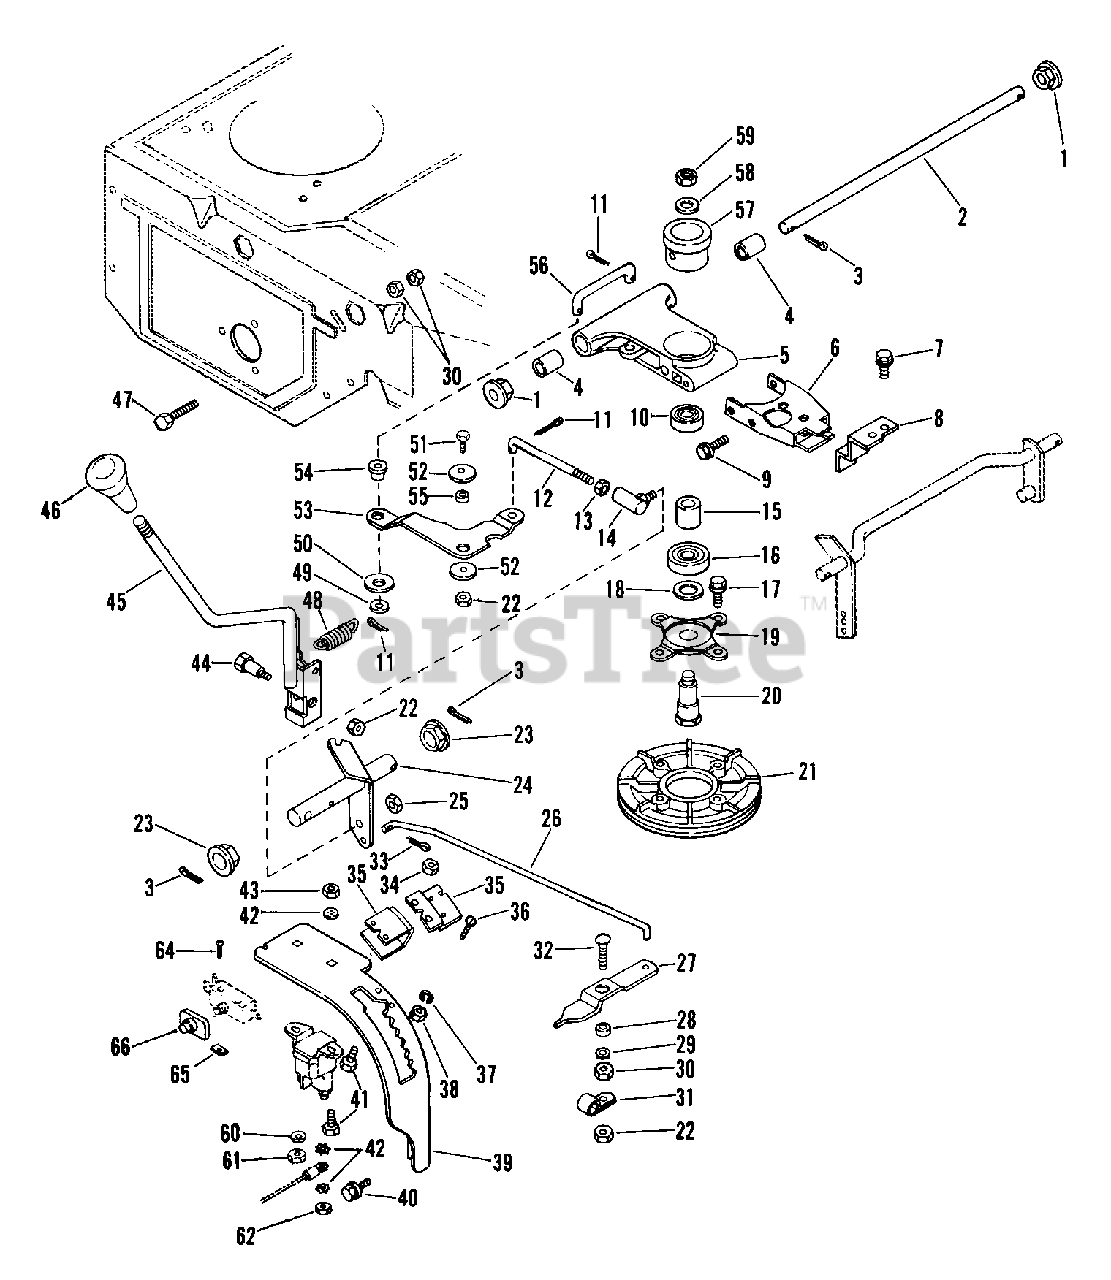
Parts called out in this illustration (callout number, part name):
1	FLANGE BUSHING
2	TRANSFER SHAFT
3	PIN-COTR .12X1.0 PL
4	BSHG-SLV .625X.750X.500 BR
5	CARRIER ASSEMBLY
6	CARRIER YOKE
7	SCR-TAP .312-18X.50 HWH PL TR
8	NEUTRAL STOP
9	SCR-TAP .312-18X.75 HWH PL TR
10	BRG-BALL .625X1.375X.44
11	PIN-COTR .09X.75 PL
12	SHIFT ROD
13	NUT-HEX .312-24 PL
14	SNAP IN BALL JOINT
15	BSHG-SLV .634X1.000X.465
16	BRG-BALL .750X1.781X.61
17	SCR-TAP.250-20X.62 HWH BLK ZC
18	WSHR-HDND-THRST .758X1.23X.031
19	DISC ADAPTER
20	SPINDLE BOLT
22	NUT-LK .312-18 GR A PL
23	FLANGE BUSHING
24	SHIFT ARM
25	NUT-LK-CTR .312-24 PL
26	INDICATOR ROD
27	INDICATOR
28	SPACER BUSHING .5 X .32 X .163
29	WSHR-FL-STL .323X.625X.062 PL
30	NUT-HEX .312-18
32	BLT-RDHDSQNK .31-18X1.0 SHT PL
33	PIN-COTR .06X.50
34	NUT-LK-CTR .250-20 PL
35	BRACKET NEUTRAL SWITCH
35	MOUNTING BRACKET NEUTRAL SWITC
36	SCR-MCH 10-24X1.00 SLRH PL
37	WSHR-LK 10X.047 MED PL
38	NUT-HEX 10-24 PL
39	QUADRANT
40	SCR-TAP .250-20X.50 HXSLHDPL
41	BLT-HEX .25-20X.50 PL GR2
42	WSHR-LK-INT .313X.030 PL
43	NUT-HEX .250-20 PL
44	SHOULDER BOLT .436 X .912
45	SHIFT LEVER
47	BLT-HEX .31-18X1.50 GR2 YWZC
48	SG-TENS .092X.69X1.75 WLD 54
49	WSHR-FL-STL .380X.626X.033
50	WSHR-FL-STL .531X1.250X.100 PL
51	BLT-HEX .31-18X.75 PL GR2
52	WSHR-FL-STL .344X1.125X.063PL
53	BELL CRANK
54	BSHG-FLG .372X.500X.312X.625NY
55	SPACER BUSHING .5 X .32 X .21
56	SHIFT LINK
57	BEARING HOUSING
58	WSHR-HDND-STL-THR.515X.97X.062
59	NUT-LK-CTR .50-20 PL
60	WSHR-LK-EXT #10 ID X .022
61	NUT 10-32 PL
62	NUT-JAM .312-24 PL
63	CABLE TIE LG 5-1/2
64	SCR-MCH 6-32X1.00 SLRH PL
65	NUT-KEPS 6-32 PL
66	SWITCH BOOT
